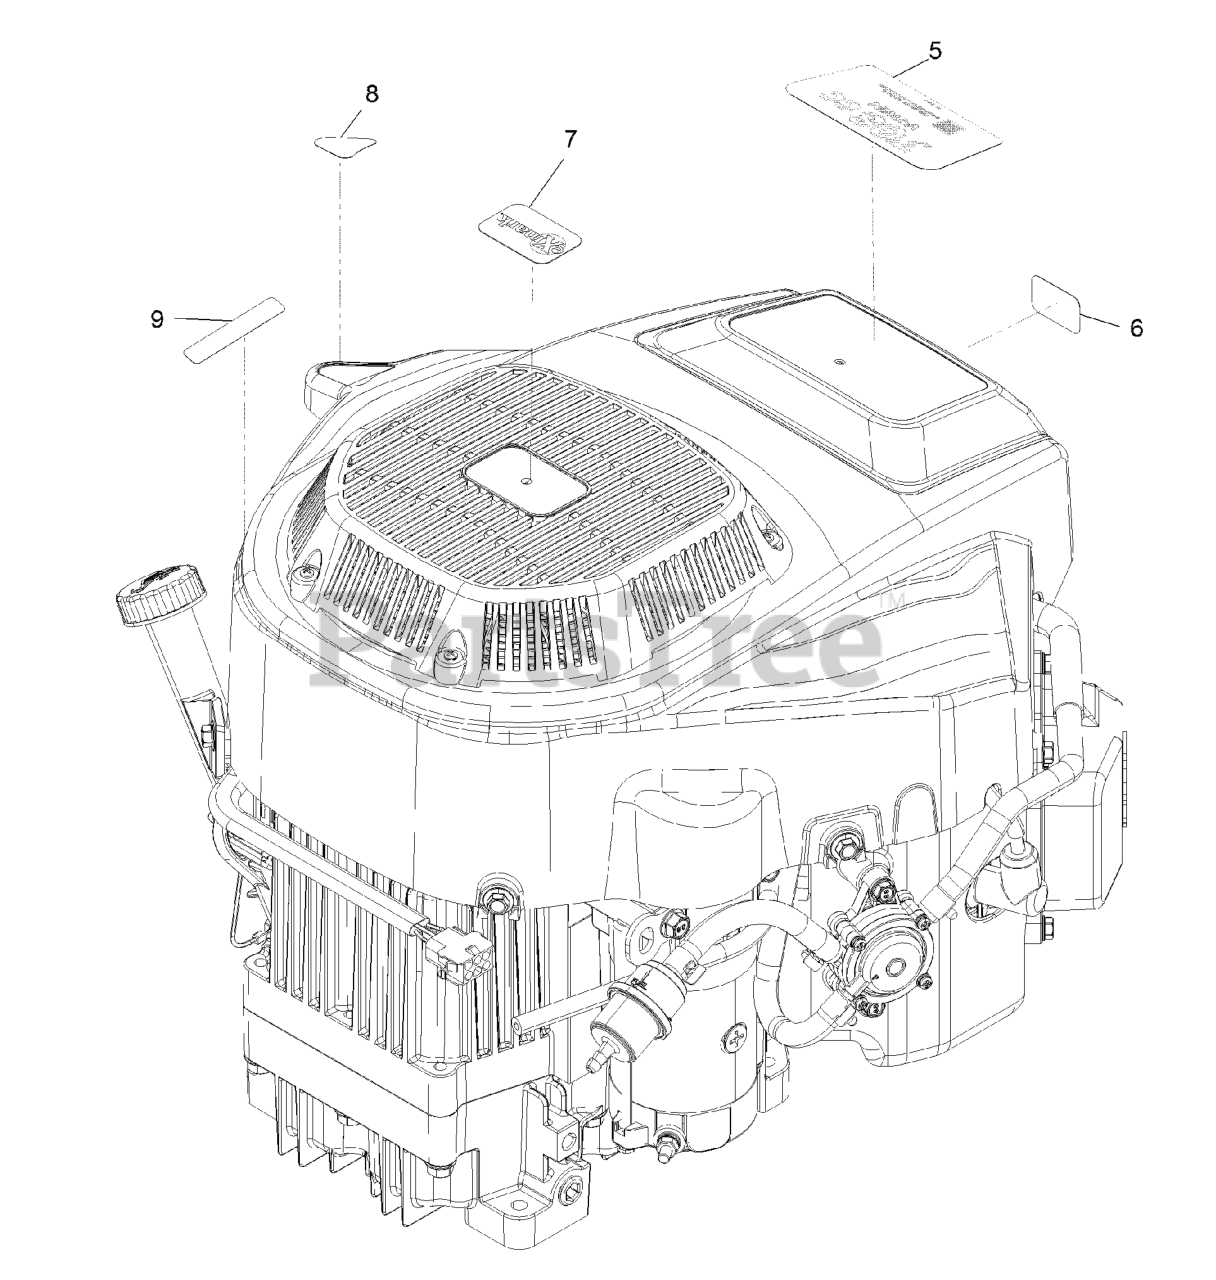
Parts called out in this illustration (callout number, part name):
5	DECAL-ENGINE DISPLACEMENT
6	PLACARD-INTAKE, EXMARK
8	DECAL-DRAIN, OIL
9	DECAL-SHUTDOWN
